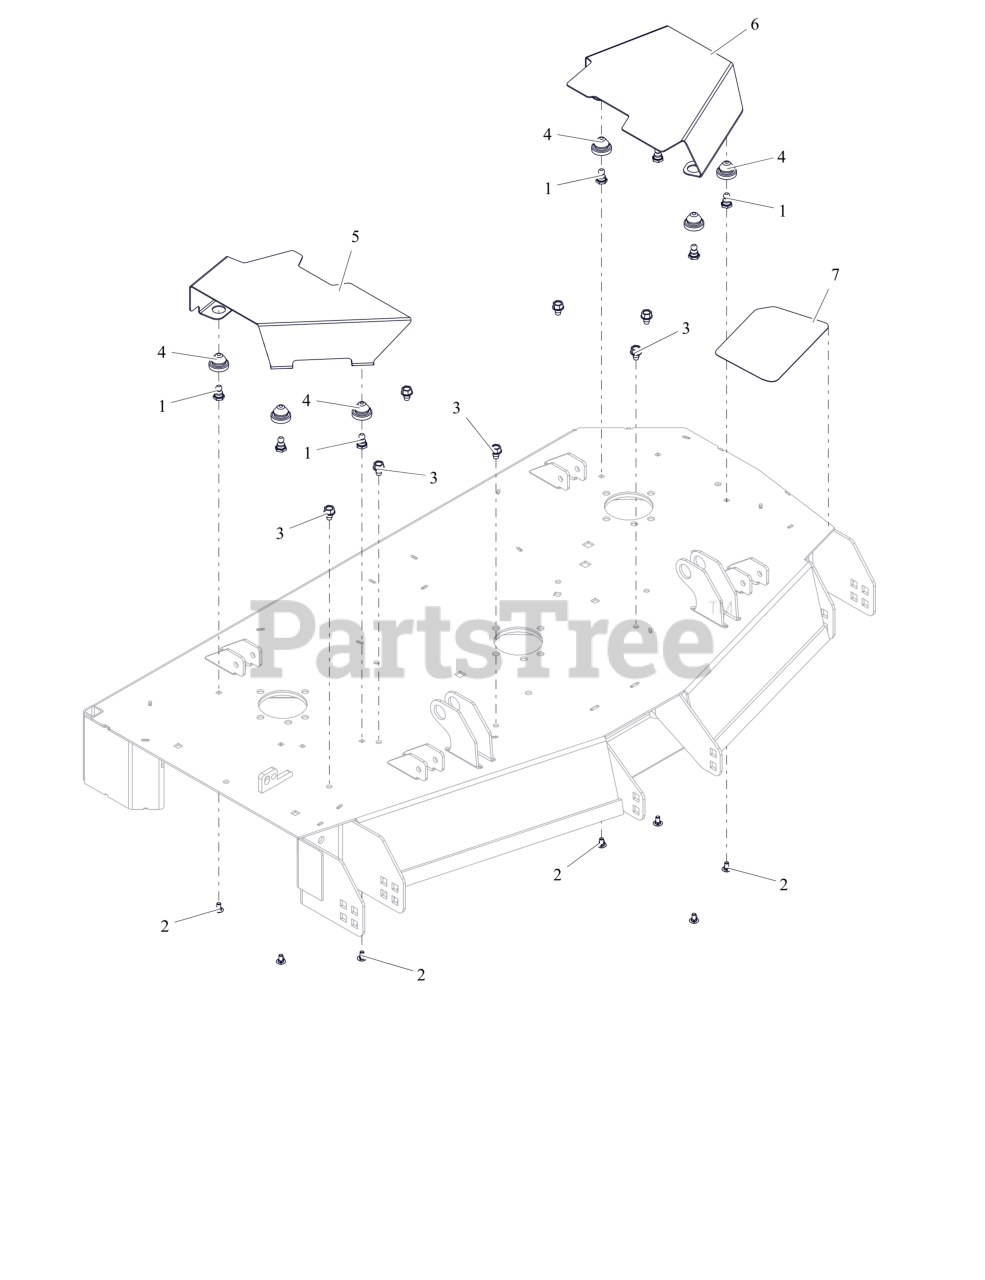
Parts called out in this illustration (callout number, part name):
1	STUD, BALL FEMALE .250-20 THREAD
2	BLT, RHSSN.25-20X.500 G5 ZCC
3	SCR,TAP .375-16X.50 HWH TR ZCC
4	COUPLING, RUBBER PUSH-IN
5	COVER- BELT 48" RIGHT
6	COVER- BELT 48" LEFT
7	GRIP, STEP ANTI SKID HD XF3
